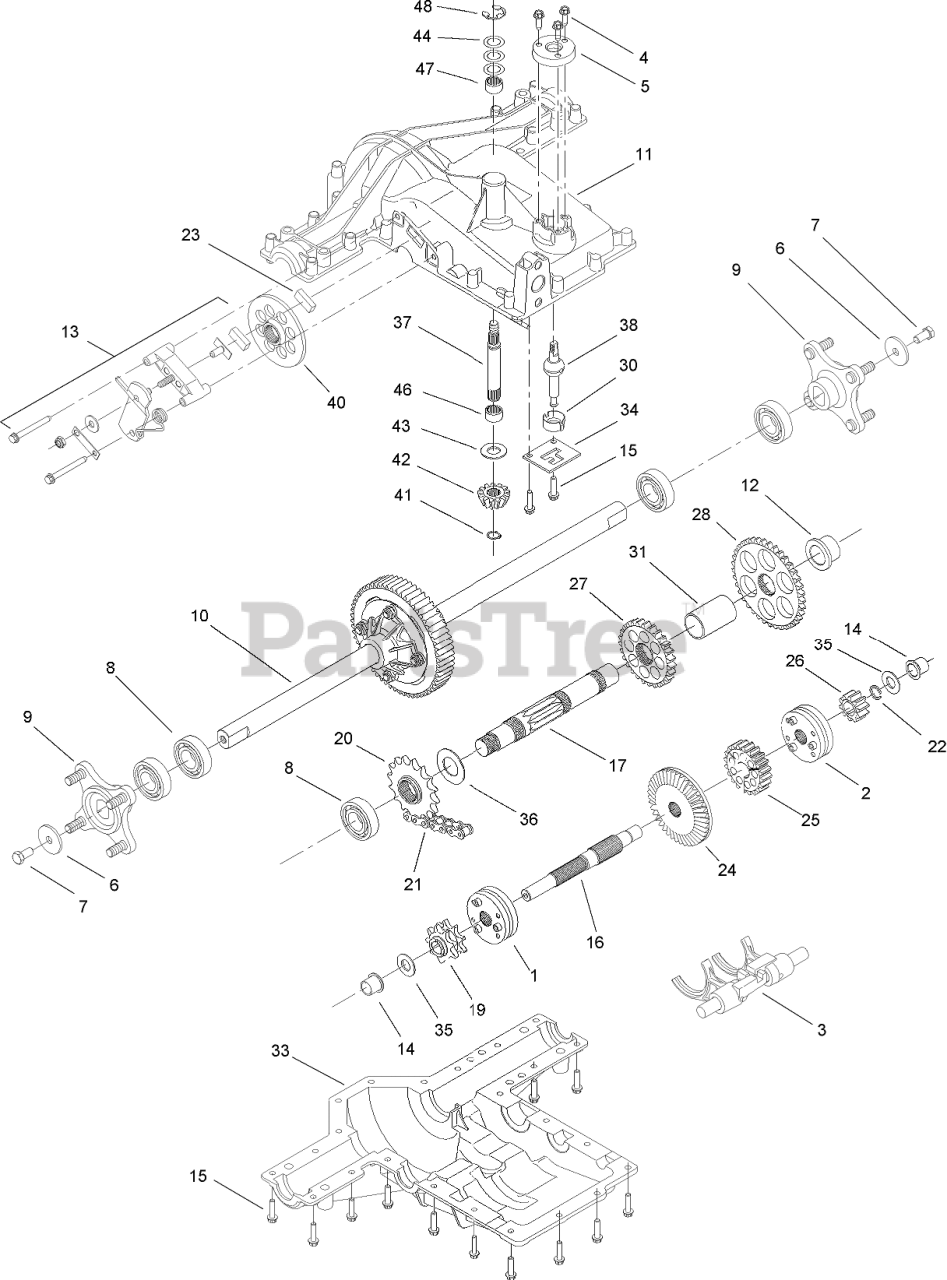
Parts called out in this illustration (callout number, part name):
1	COLLAR ASM
2	HI-LO COLLAR ASM
3	SHIFT FORK ASM
4	SCREW-TAP
5	COVER-SHIFT
6	WASHER-FLAT
7	SCREW-HH
8	BEARING-BALL
9	WHEEL HUB ASM
10	DIFFERENTIAL AXLE ASM
11	HOUSING-UPPER
12	BEARING-FLANGED
13	RH BRAKE ASM
14	BEARING-FLANGE (W/KEY)
15	SCREW-TAP
16	SHAFT-DRIVE
17	SHAFT-OUTPUT, RH
19	SPROCKET-9T
20	SPROCKET-16T
21	CHAIN-LINK, 22
22	RING-SNAP
23	PUCK-BRAKE
24	GEAR-SPUR 41T
25	GEAR-SPUR 20T
26	GEAR-SPUR 10T
27	GEAR-SPUR, 27T
28	GEAR-SPUR, 37T
30	INSERT-SHIFTER
31	COVER-SHIFTER
33	HOUSING-LOWER
34	PLATE-LOCKOUT
35	WASHER-FLAT
36	WASHER-FLAT
37	SHAFT-INPUT
38	LEVER-SHIFT
40	BRAKE-DISC, 43T
41	RING-SNAP
42	GEAR-BEVEL, 13T
43	WASHER-THRUST
44	WASHER-FLAT
46	BEARING-NEEDLE
47	BEARING-NEEDLE
48	RING-E
